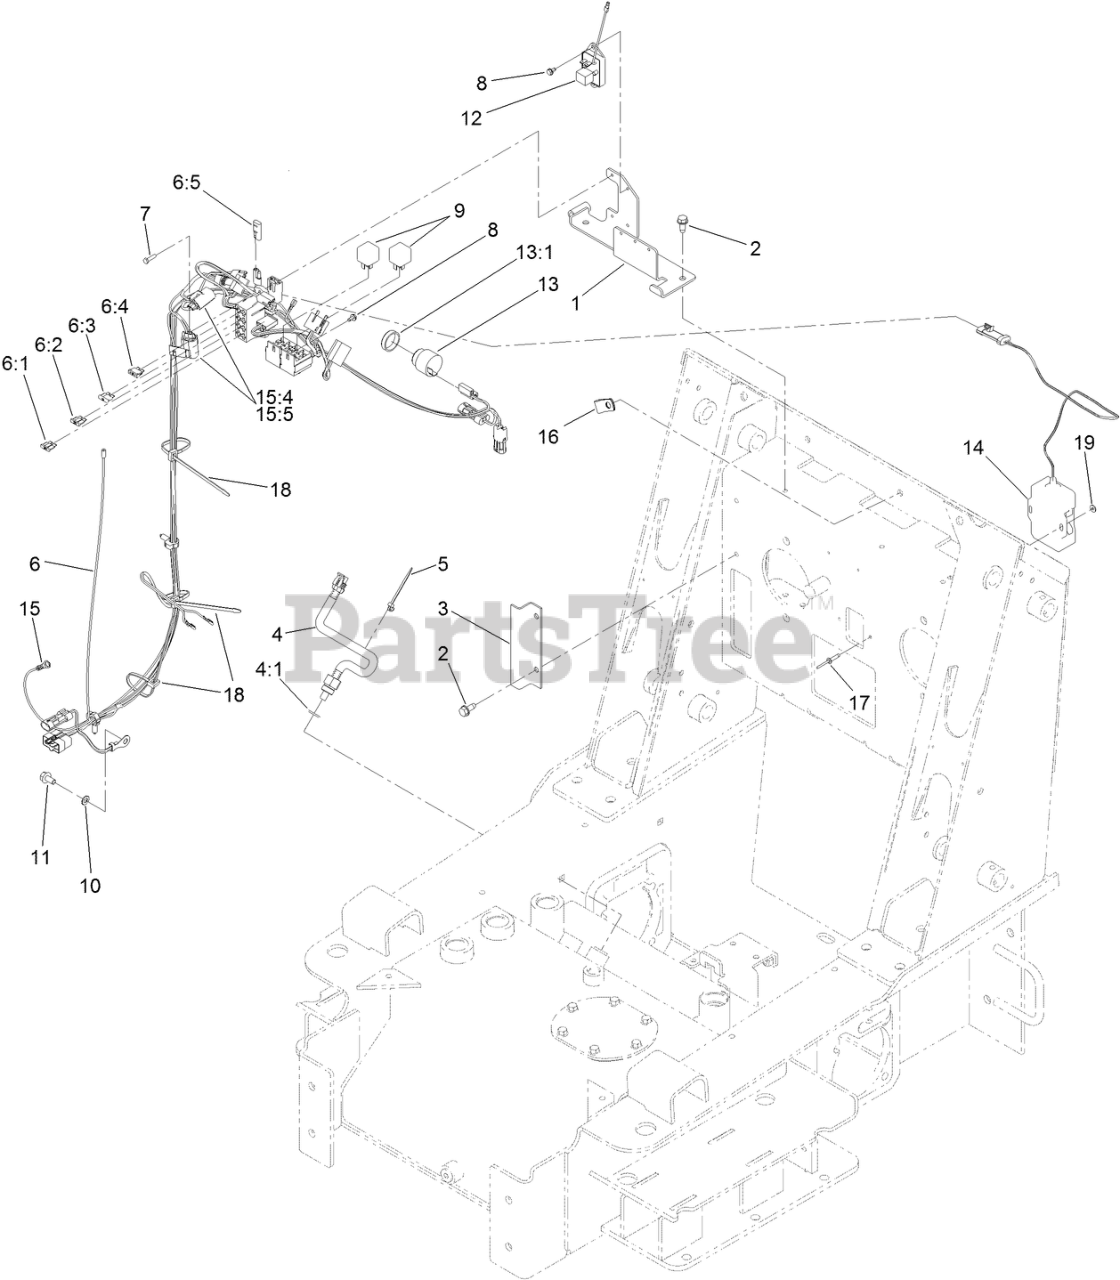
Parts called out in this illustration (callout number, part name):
1	BRACKET-FUSE/RELAY
2	SCREW-THD ROLL, HWH
3	SHIELD-WIRING
4	SWITCH-TEMPERATURE
4:1	O-RING
5	TIE-CABLE
6	HARNESS-WIRE
6:1	FUSE-BLADE, 30 AMP
6:2	FUSE-BLADE, 25 AMP
6:3	FUSE-BLADE, 10 AMP
6:4	FUSE-BLADE, 15 AMP
6:5	CAP-PLUG
7	SCREW
8	SCREW-HWH
9	RELAY
10	WASHER-LOCK
11	SCREW-HHF
12	MODULE-IGNITION DELAY
13	AUDIO ALARM ASM
13:1	NUT-PLASTIC, KNURLED
14	GPS ASM
15	HARNESS-WIRE, GPS
15:4	FUSE-MINI BLADE, 5 AMP
15:5	COVER-FUSE, SINGLE
16	CLAMP-R
17	RIVET-POP
18	TIE-CABLE
19	WASHER-PLAIN
